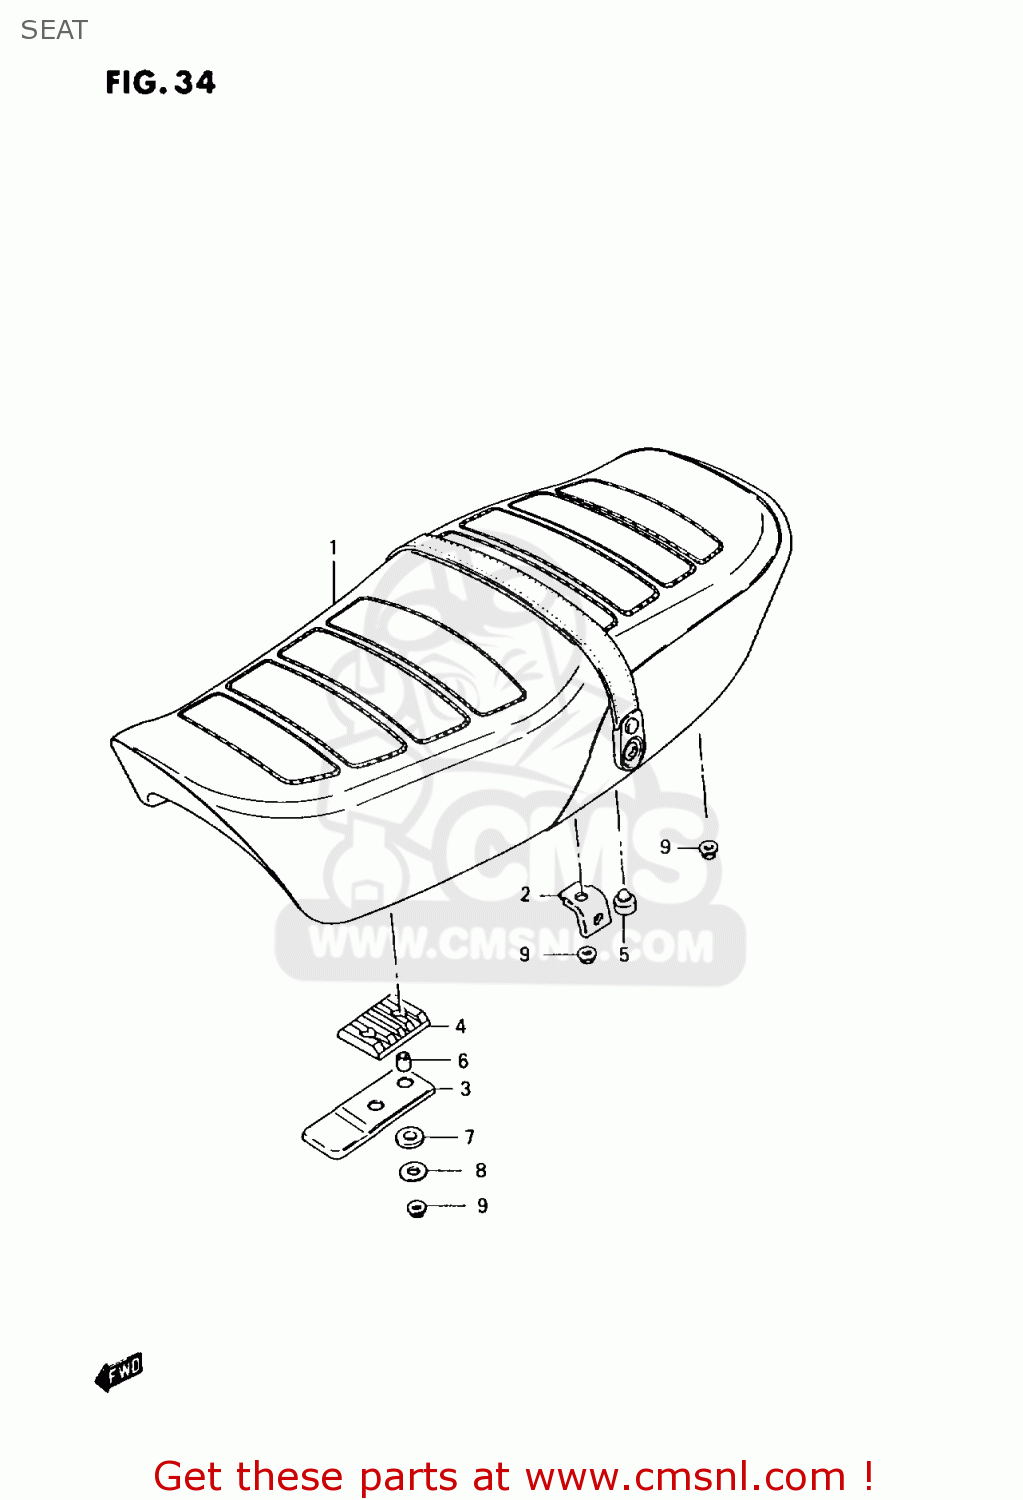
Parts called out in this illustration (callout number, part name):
1	SEAT ASSY (BLACK)
2	BRACKET,SEAT CTR
3	PLATE,SEAT HOOK FR
4	CUSHION,FR PLATE
5	CUSHION(11.5X22X20)
6	SPACER,SEAT BRACKET
7	CUSHION,SEAT FR
8	WASHER
9	NUT
